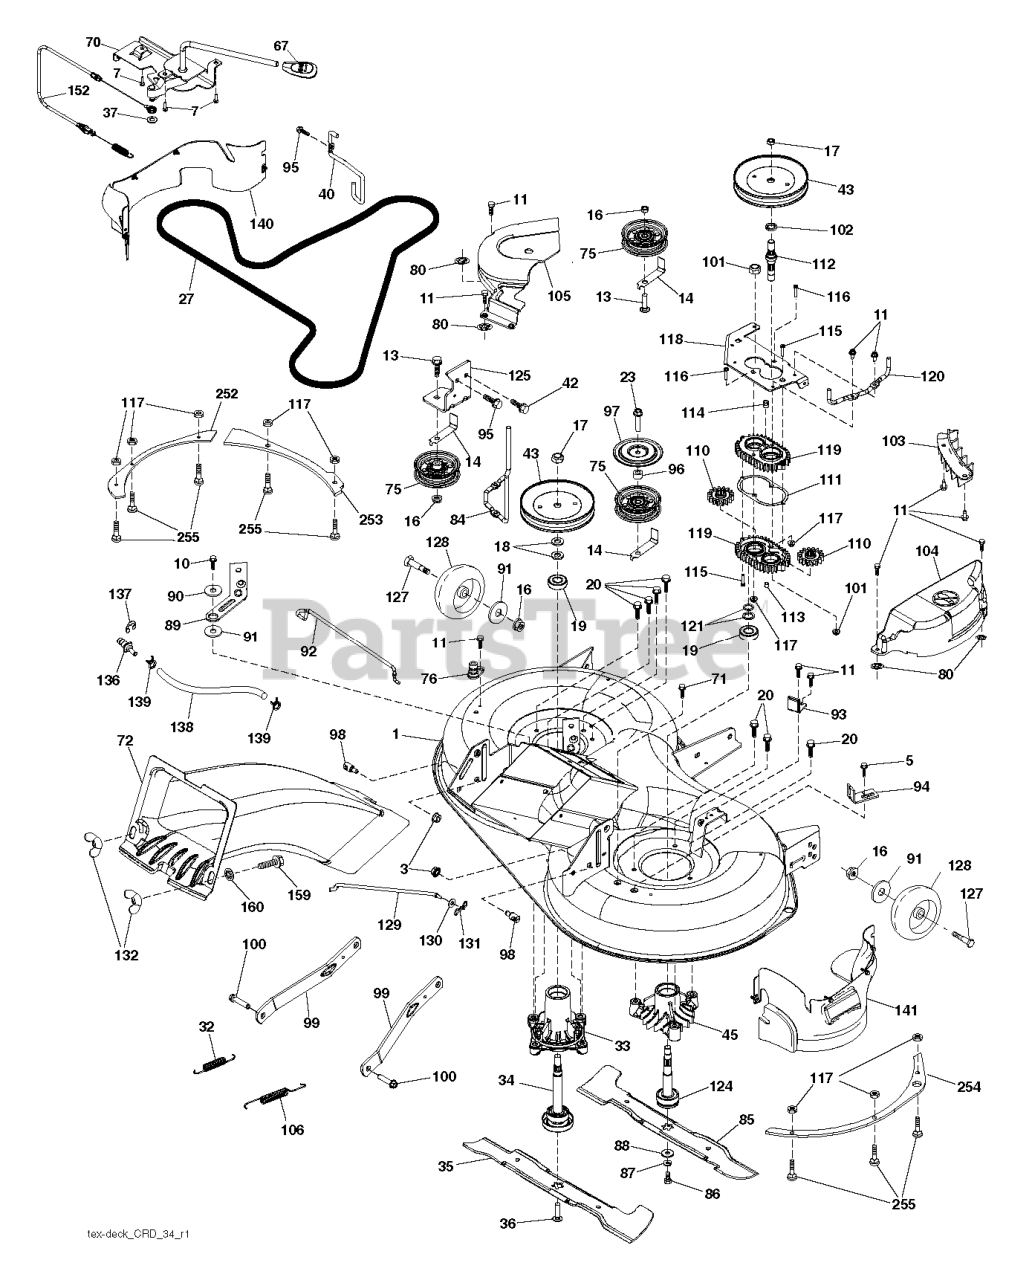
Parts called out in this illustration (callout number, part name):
1	DECK.WELDMENT.97.TEX.498
3	NUT LOCK HEX FLANGE 5/16-18
5	BOLT.5/16HEX.WHS.HD
7	SCREW.#10 X 0.750.BOS
10	SCREW 3/8-16X1
11	SCREW.1/4-20X5/8
13	BOLT.3/8-16X1.50
14	KEEPER, BELT IDLER
16	NUT LOCK FLG 3/8-16 UNC
17	NUT.FLANGE.LOCK.TOP
18	WASHER.SPACER.MANDREL
20	SCREW, WASHER HEAD
23	SCREW LT
27	BELT V-BELT DRIVE
32	SPRING RETURN
33	RP.HOUSING.MANDREL.4PT.
34	SHAFT.ASM.MDRL.N/GREASE.38
35	BLADE.3N1.LH.CRD.97
36	BOLT.WASHER.ASM.7/16-2
37	WASHER
40	KEEPER BELT ENGINE LH
42	SCREW
43	PULLEY.MANDREL.5.438.PD
45	HOUSING.MANDREL.44/46" VENT
67	HANDLE.CLUTCH.CABLE.LT
70	CLUTCH.ASM.MANUAL.LT.PRED
71	SCREW 3/8-16X1/2
72	CHUTE REAR CRD UPPER CHUTE TEX
75	FLAT IDLER PULLEY
76	1/2" BARB.DECK.WASHOUT.PORT
80	PALNUT 1/4
84	KEEPER.BELT.MANDREL.PULLEY
85	BLADE.3N1.RH.CRD.97
86	BOLT.3/8-24X1.25GR8. LHTHRD
87	LOCKWASHER
88	WASHER.BLADE
89	ARM.BRAKE.97.LH
90	SPACER.RETAINER
91	WASHER
92	ROD ROD BRAKE
93	ARM.BRAKE.97.RH
94	BRKT.CLUTCH.CABLE
95	SCREW, 3/8-16X3/4
96	SPACER
97	PROTECTOR
98	STUD.FASTNER.W/ANTI-ROTATE
99	ARM.SUSPENSION.MOWER.R
100	BOLT.SHOULDER
101	NUT.CROWNLOCK.9/16 -18.UNC
102	SPACER BEARING
103	GUARD GUARD FRONT VENT
104	97.CRD.RH.MANDREL.COVER
105	MANDREL MANDREL COVER LH
106	SPRING.BRAKE.RETURN.38"
110	CRD.SPUR.GEAR
111	GASKET GASKET GEARCASE
112	SHAFT SHAFT. CRD GEARCASE ADAP
113	PLUG PLUG OIL
114	VALVE VALVE RELIEF
115	SCREW
116	BOLT.CARIGE.SS.1/4-20X1.75GR5
117	NUT T
118	ARM ARM CLUTCHING
119	GEARCASE GEARCASE SUBASM
120	BRACKET KEEPER BELT RH
121	WASHER WASHER
124	MANDREL SHAFT NON/GREASE
125	BRACKET
127	BOLT.SHOULDER.3/8-16X3-5/8.
128	RP WHEEL. GUAGE RALLY
129	ROD.ANTI.SWAY.48/54"K4
130	WASHER
131	PIN.COTTER.5/16.BOW TI
132	KNOB.HANDLE.3/8.TRI-POINT.BLAC
136	PLUG WASHOUT PORT HOOKUP
138	HOSE.3/8ID.BULK.12"
139	HOSE.3/8.CLAMP (2 2)
140	GUARD
141	GUARD SUBASM.TEX CRD 97CM RH F
152	CABLE CABLE CLUTCH MANUAL W/S
159	BOLT
252	PLATE.REINFORCEMENT.LHS.X431
253	PLATE.REINFORCEMENT.LHS.X431
254	PLATE.REINFORCEMENT.X431
255	RHSNB, 1/4-20 X 1, GR5
